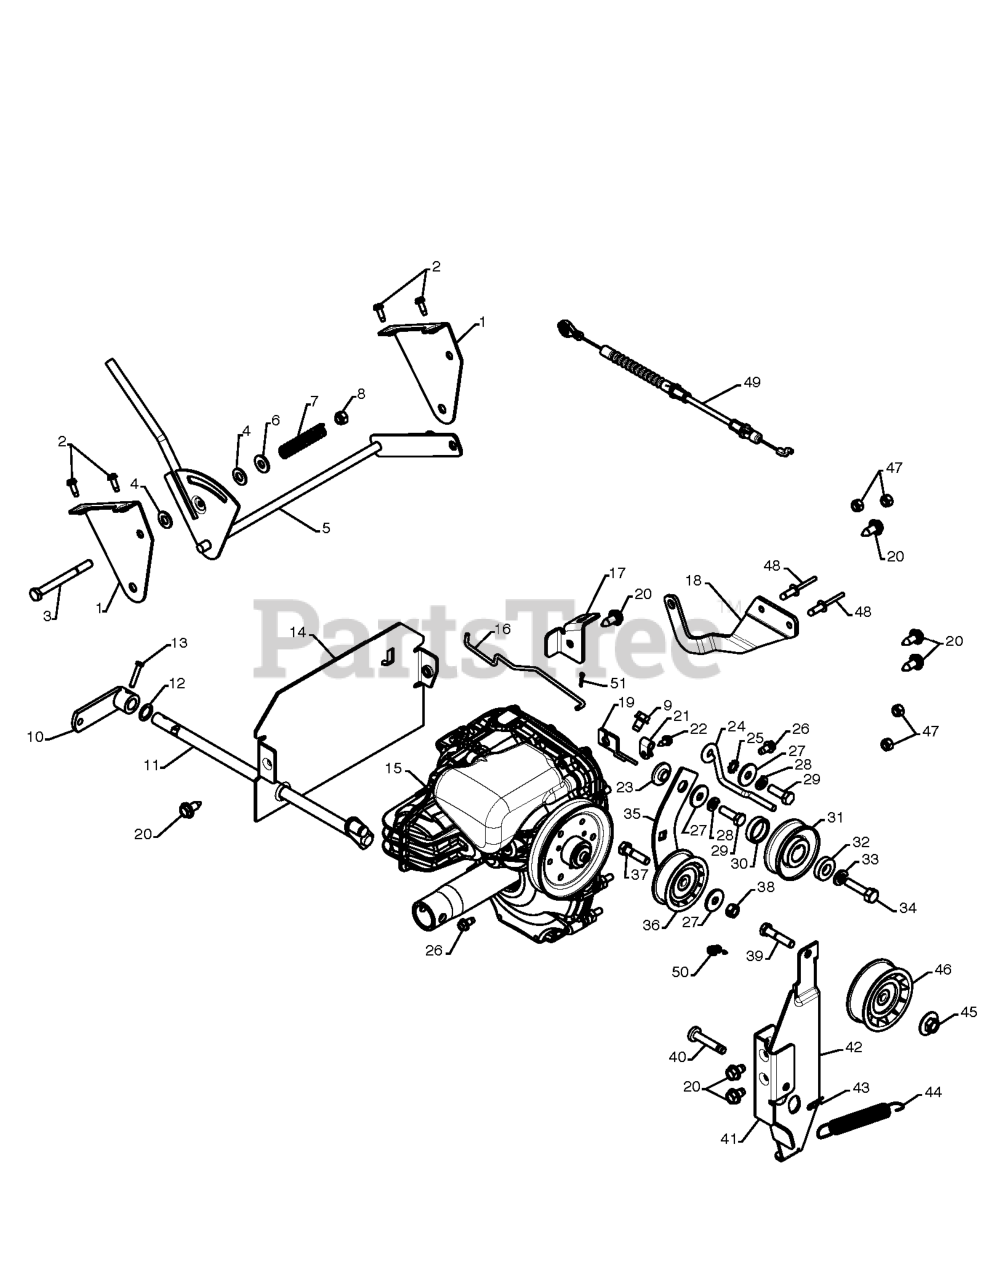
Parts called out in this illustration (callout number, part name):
1	BRACKET, SHIFT
2	SCREW #10-24 X 5/8
3	SCREW 5/16-18 X 3.25
4	WASHER, NYLON FRICTION
5	LEVER ASSEMBLY, SPEED CONTROL
6	WASHER.20X8.5
7	SRPING.FRICTION.HYDRO
8	NUT.71038.31-18.HEX.NYLOCK
9	Screw 5/16-18 x 1/2 Hex, Self Tapping 5/16-18 x 1/2
10	ARM.CONTROL.AUGER
11	SHAFT, AUGER CONTROL
12	THRUST WASHER
13	CLEVIS PIN
14	PLATE.REAR.HYDRO.ORANGE
15	TRANSMISSION.HYDRO.SNOW
16	ROD, BYPASS VALVE
17	BRACKET.CABLE.REAR.SNOW
18	ARM.CONTROL.HYDRO.SNOW
19	BRACKET, CABLE, FRONT
20	SELF-TAPPING SCREW 5/16-18X3/4
21	GUIDE CLIP PM
22	SCREW, SLOTTED HEX HEAD 1/8 X
23	RP BUSHING, IDLER PIVOT
24	GUIDE, BELT
25	WASHER EXT TOOTH LOCK 5/16
26	SCREW
27	STEEL WASHER
28	WASHER.LOCK.HVY.HLCL.SPR.5/16
30	SPACER.ENGINE.PULLEY
31	PULLEY,ENGINE TRACTION DRIVE
32	WASHER, FLAT 3/8
33	LOCKWASHER
34	SCREW, HEX HD 3/8-24 X 1-3/8
35	ARM, IDLER
36	PULLEY.W/SPACER.2.25
37	BOLT.5/16-18X1-1/4 FULL.THREAD
38	NUT.CENTERLOCK.5/16-
39	HEX BOLT
40	PIN, IDLER PIVOT
41	BRACKET, PIVOT, IDLER
42	ARM.IDLER.BRAKE.BLACK
43	RETAINER CLIP PM
44	SPRING, BRAKE
45	LOCKNUT 5/16-18
46	PULLEY.W/SPACER.2.75
47	LOCKNUT.NYLOC.1/4-20
48	RIVET.POP.1/4X.475
49	CABLE.DRIVE.CONTROL.SNOW
50	SPRING, TRACTION IDLER
51	RETAINER CLIP
